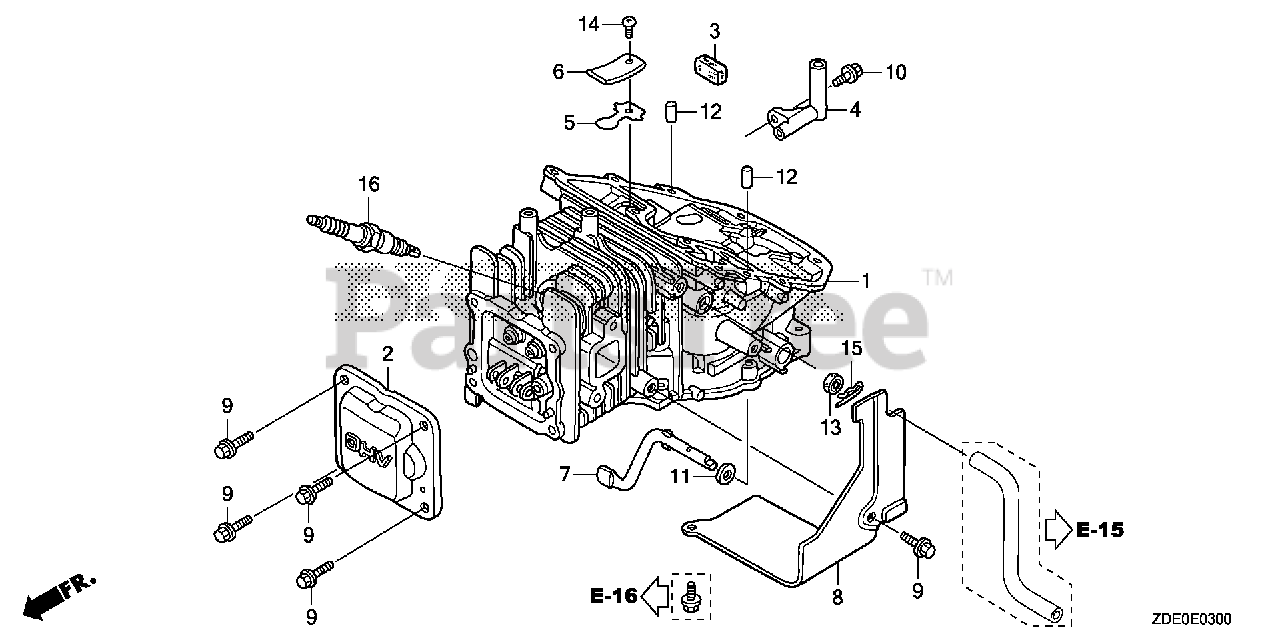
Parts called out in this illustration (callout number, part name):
2	COVER, HEAD
3	FILTER, BREATHER
4	PIPE, BREATHER
5	VALVE, OIL OUTLET
6	PLATE, STOPPER
7	SHAFT, GOVERNOR ARM
9	BOLT, FLANGE (5X12)
10	BOLT (4X10)
11	WASHER (5.2X9)
12	ROLLER (6X14.8)
13	OIL SEAL (5X11X5)
14	SCREW, PAN (3X5)
15	PIN, LOCK (6MM)
16	SPARK PLUG (U14FSR-UB) (DENSO)
16	SPARK PLUG (CR4HSB) (NGK)
16	SPARK PLUG (U16FSR-UB) (DENSO)
16	SPARK PLUG (CR5HSB)
